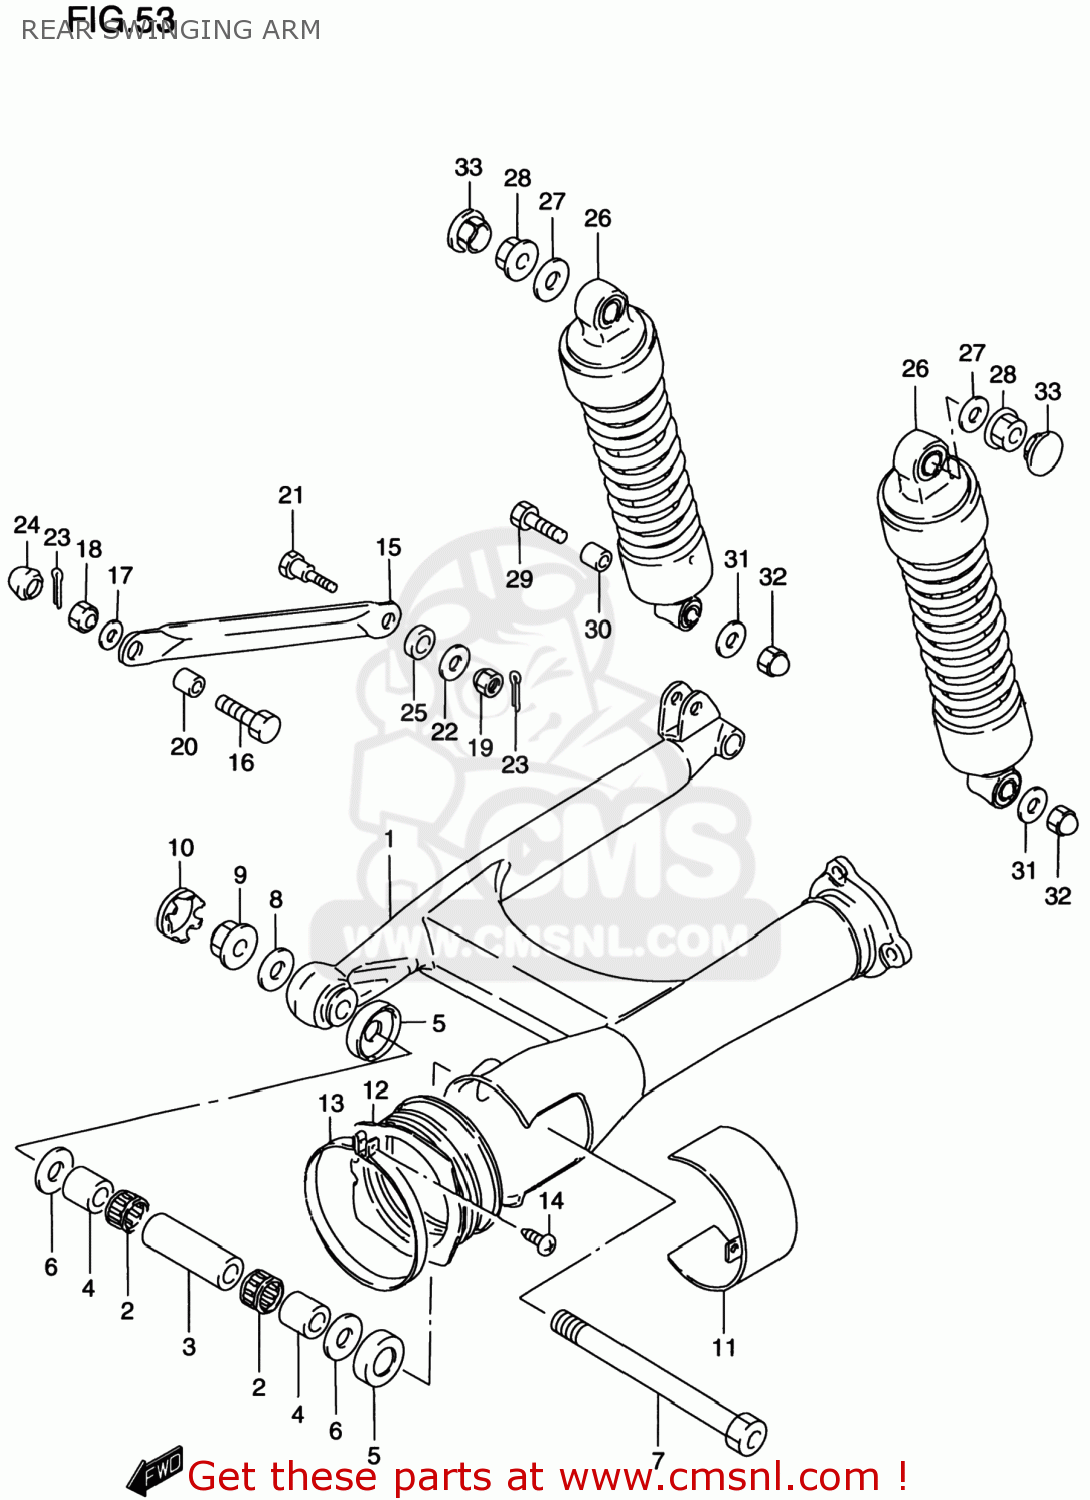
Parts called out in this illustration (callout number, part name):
1	SWINGINGARM,RR
2	BEARING(22X29X20)
3	SPACER,RR SWGARM PIVOT
4	SPACER,RR SWGARM PIVOT
5	SEAL,RR SWGARM PIVOT DUST
6	WASHER
7	SAHFT,RR SWGARM PIVOT
8	WASHER(17X30X3)
9	NUT 16MM
10	CAP,RR SWINGING ARM PIVOT,R
11	COVER,REAR SWING ARM PIVOT
12	BOOT,PROPELLER SHAFT
13	CLAMP
14	SCREW
15	TORQUELINK,RR
16	BOLT(10X28)
17	WASHER (10X20X2.3)
18	NUT
19	NUT
20	SPACER(10.2X14X9.6)
21	BOLT(10X41)
22	WASHER (10X20X2.3)
23	PIN 16X20
24	CAP
25	CUSHION
26	ABSORBER ASSY,RR SHOCK
27	WASHER(10.5X20X2.3)
28	NUT
29	BOLT(10X39)
30	SPACER(10.2X14X20.7)
31	WASHER (10.5X24X2.3)
32	NUT
33	CAP,FRAME HANDLE GRIP
